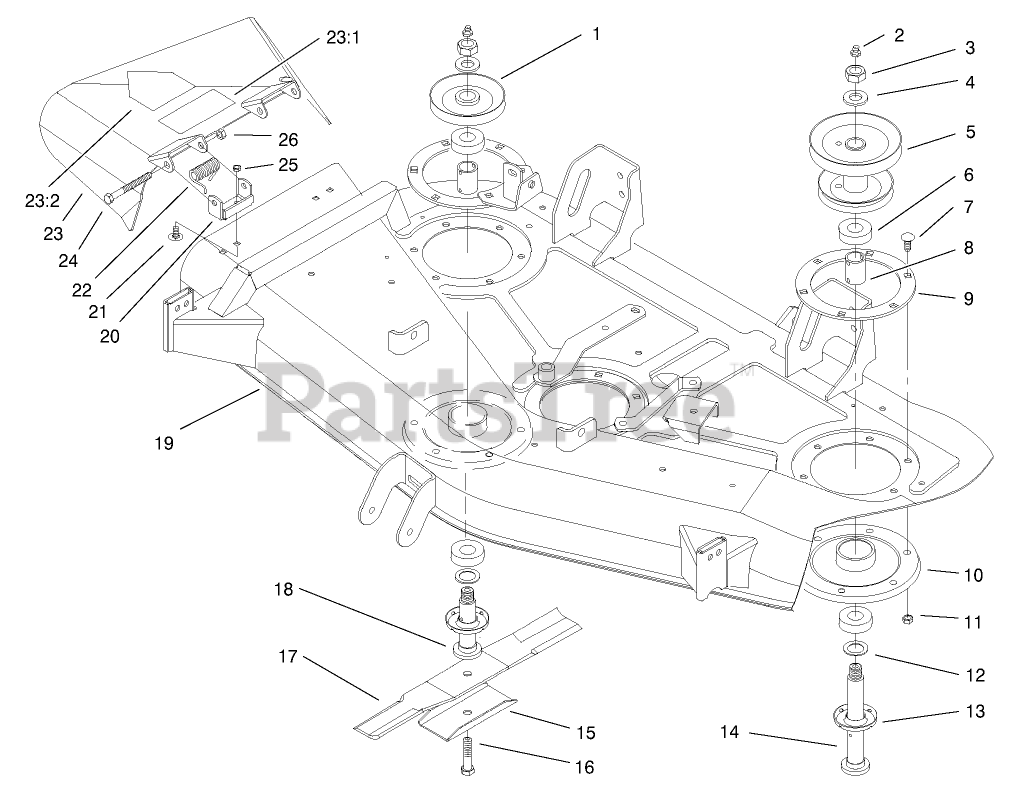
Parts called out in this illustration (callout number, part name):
1	PULLEY
2	FITTING-GREASE
3	NUT-JAM
4	WASHER-FLAT
5	PULLEY-DOUBLE
6	BEARING-BALL
7	SCREW-CARR
8	SPACER-BEARING
9	RING-DECK SUPPORT
10	HOUSING-SPINDLE
11	NUT-HF
12	WASHER-BACKUP
13	SHIELD-BEARING
14	SHAFT - SPINDLE
15	STIFFENER-BLADE
16	SCREW-BLADE
17	Blade
18	SHAFT-SPINDLE
19	DECK ASM
20	BRACKET-PIVOT
21	SCREW-CARR
22	SPRING
23	Deflector ASM
23:1	DECAL-DANGER
23:2	DECAL-DANGER
24	SCREW-HH
25	NUT-LOCK, NI
26	NUT-HEX
